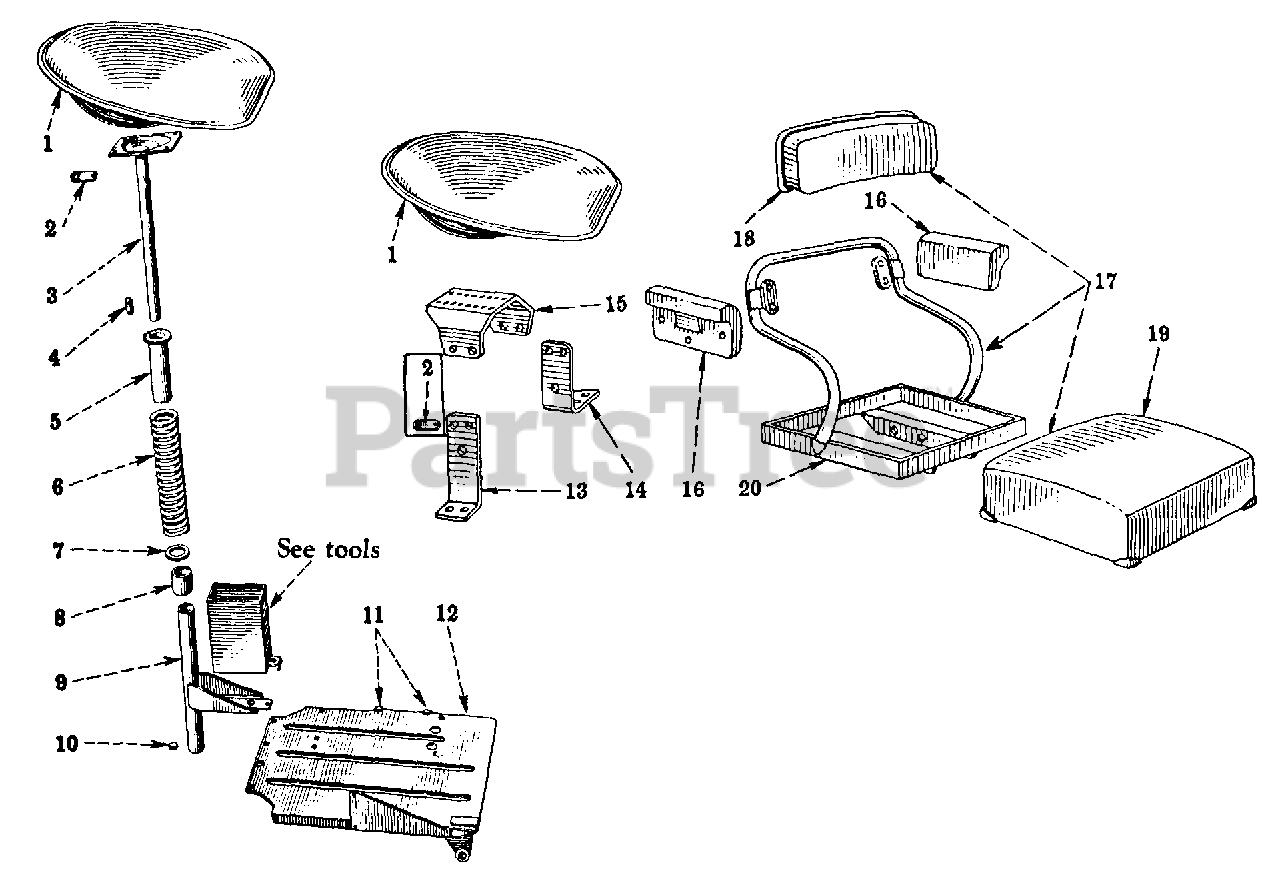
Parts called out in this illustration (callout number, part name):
1	SEAT ASSY, UPHOLSTERED
3	POST ASSY, SEAT
4	GUIDE, SEAT POST
5	RETAINER ASSY, SEAT SPRING
6	SPRING, SEAT
7	WASHER, SEAT SPRING
8	SPACER SEAT SPRING
9	TUBE, SEAT SUPPORT
10	SHOCK ABSORBER, SEAT POST
11	CLIP, STARTING CRANK
12	PLATFORM ASSY
13	SUPPORT DELUXE CUSHION SEAT RH
14	SUPPORT, DELUXE CUSHION SEAT LH
15	BRACKET, SEAT SUPPORT
16	PAD W/CLAMP, DELUXE CUSHION SEAT ARMREST
17	SEAT ASSY DELUXE CUSHION
18	REST ASSY DELUXE SEAT
19	CUSHION ASSY, DELUXE SEAT
20	FRAME ASSY, DELUXE SEAT
